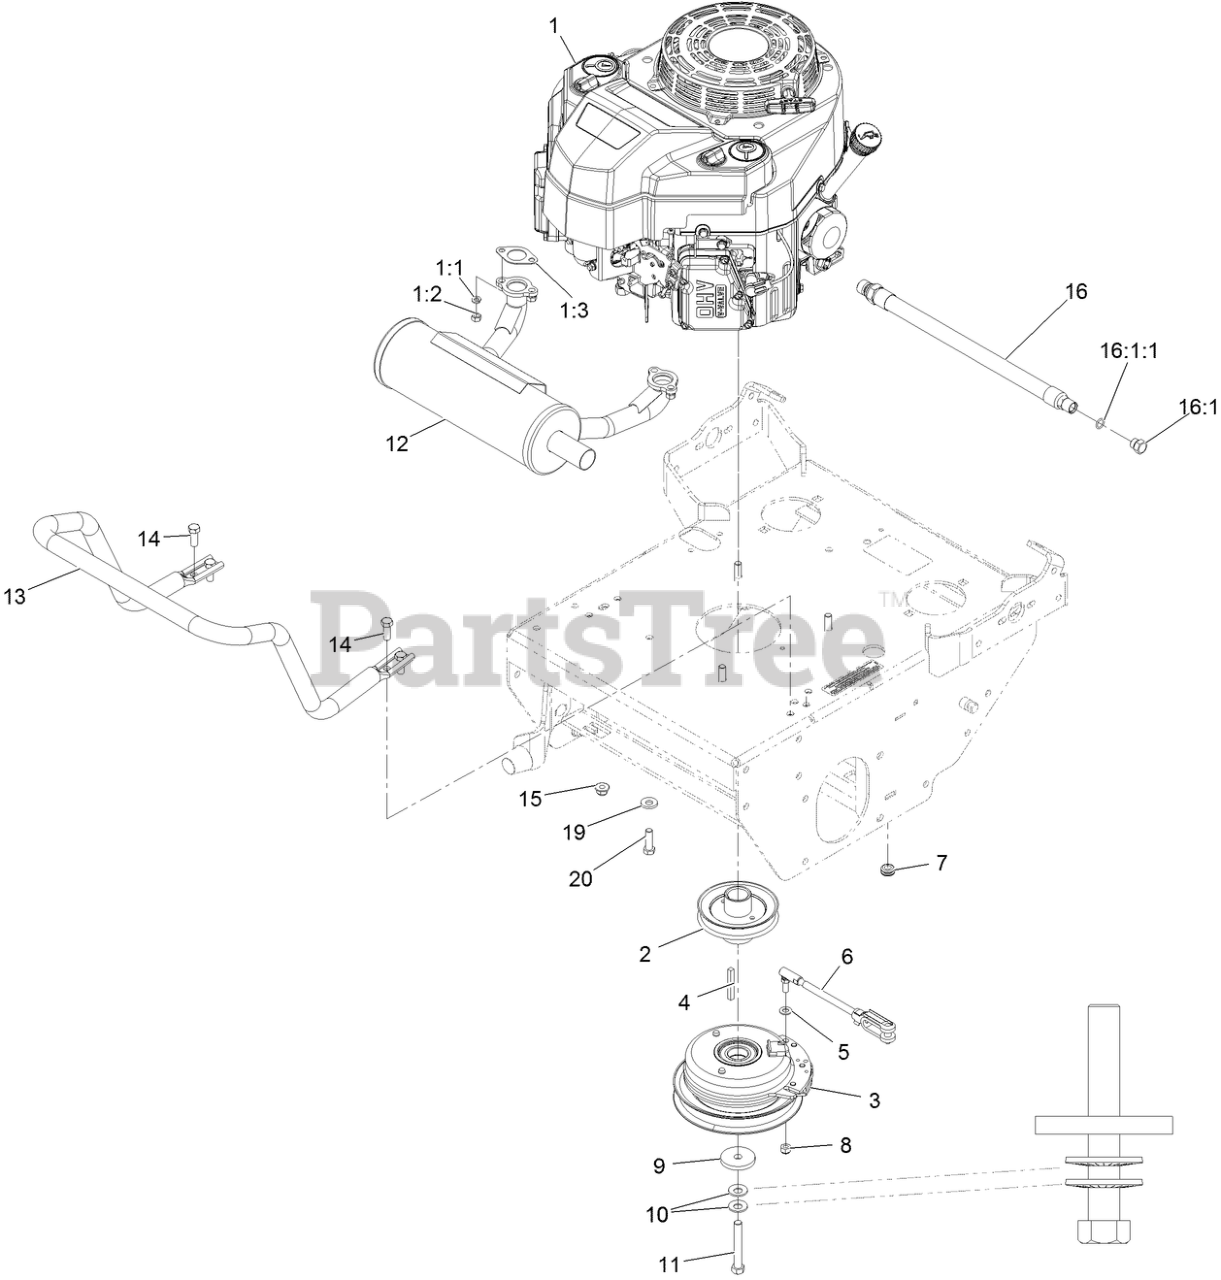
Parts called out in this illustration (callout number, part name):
1:1	WASHER-LOCK
1:3	GASKET-EXHAUST
2	SHEAVE, W/ HUB
3	CLUTCH, 105 FT/LBS, 1.13
4	KEY-SQUARE
5	WASHER-PLAIN
6	ASM, CLUTCH ANCHOR
7	GROMMET
8	NUT-LOCK
9	WASHER-CLUTCH
10	WASHER-SPRING
11	SCREW-HH
12	MUFFLER-HORIZONTAL
13	TUBE-GUARD MUFFLER
14	SCREW-HH
15	NUT-HF, NI
16	ASM, ENGINE OIL DRAIN HOS
16:1	PLUG-HH
16:1:1	O-RING
19	WASHER-BELLEVILLE
20	SCREW-HH
